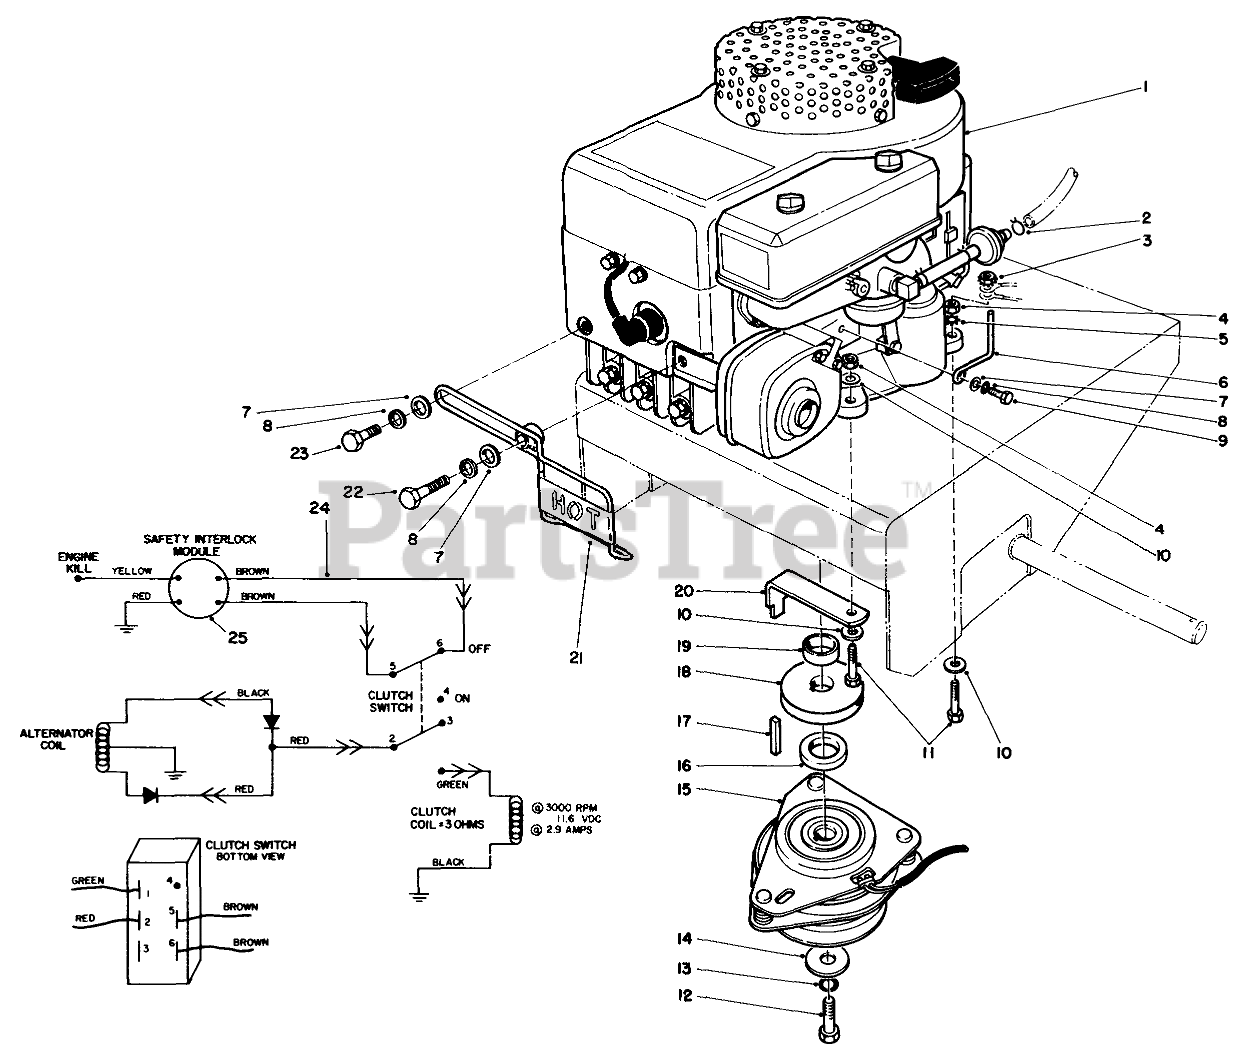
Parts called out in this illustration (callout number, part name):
1	Engine 12 H.P.
2	CLAMP-HOSE
3	NUT-KEPS
4	NUT-LOCK, CONE
5	WASHER-LOCK
6	BRUSH GUARD
7	WASHER-FLAT
8	WASHER-LOCK
9	SCREW-HH
10	WASHER-PLAIN
11	SCREW-HH
12	SCREW-HH
13	WASHER-LOCK
14	WASHER-CLUTCH
15	CLUTCH/BRAKE
16	SPACER-LOWER
17	KEY-SQUARE
18	Pulley-Drive
19	Spacer-Upper
20	Retainer-Clutch
21	MUFFLER SHIELD WA
22	SCREW-HH
23	SCREW-HH
24	Wire Harness (Incl. Ref. #25)
25	Module
